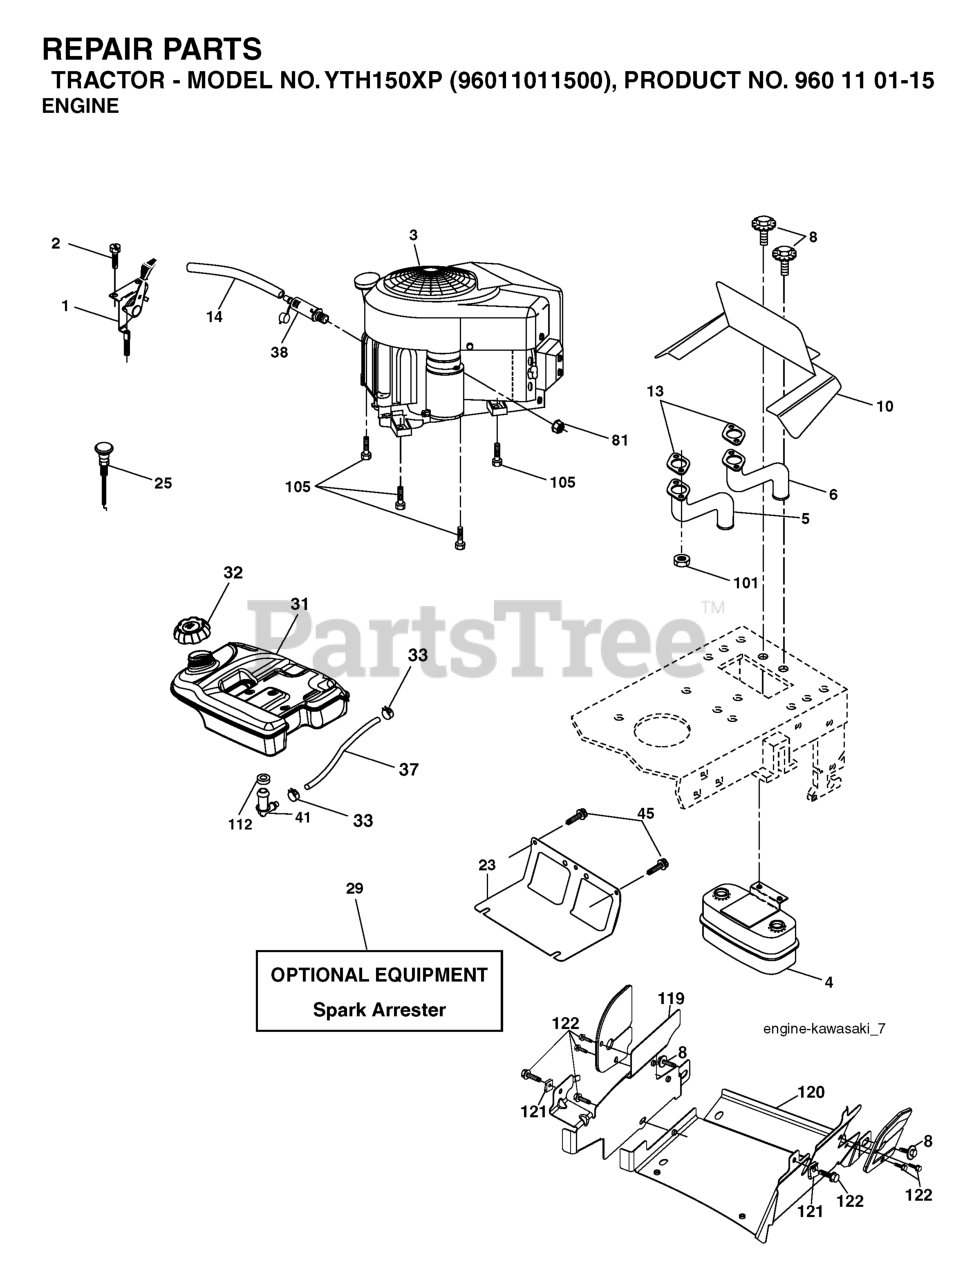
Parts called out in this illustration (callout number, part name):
1	CONTROL, THROTTLE
2	SCREW
4	MUFFLER.TWIN.CYL.LOW.TONE
5	EXHAUST TUBE LH KAWI
6	EXHAUST TUBE RH KAWI
8	BOLT.5/16-18UNCX3/4 W/SEMS.BLK
10	RP SHIELD HEAT MUFFLER
14	TUBE, DRAIN OIL ASM.
23	SHIELD.BROWNING.DBR.GUARD
29	KIT.SPARK ARRESTOR 794945 B&S
31	4.0 REAR FUEL TANK
32	TANK CAP
33	HOSE CLAMP
37	REPL BY 532 00 85-43
41	STEM FUEL TANK
45	SCREW, 3/8-16X3/4
81	NUT
101	NUT.HEX.FLANGE.TOPLOCK
105	SCREW 3/8-16X1
112	BUSHING OUTLET T
122	SCREW.1/4-20X5/8
123	SCREW, 5/16-18 X 1/2
